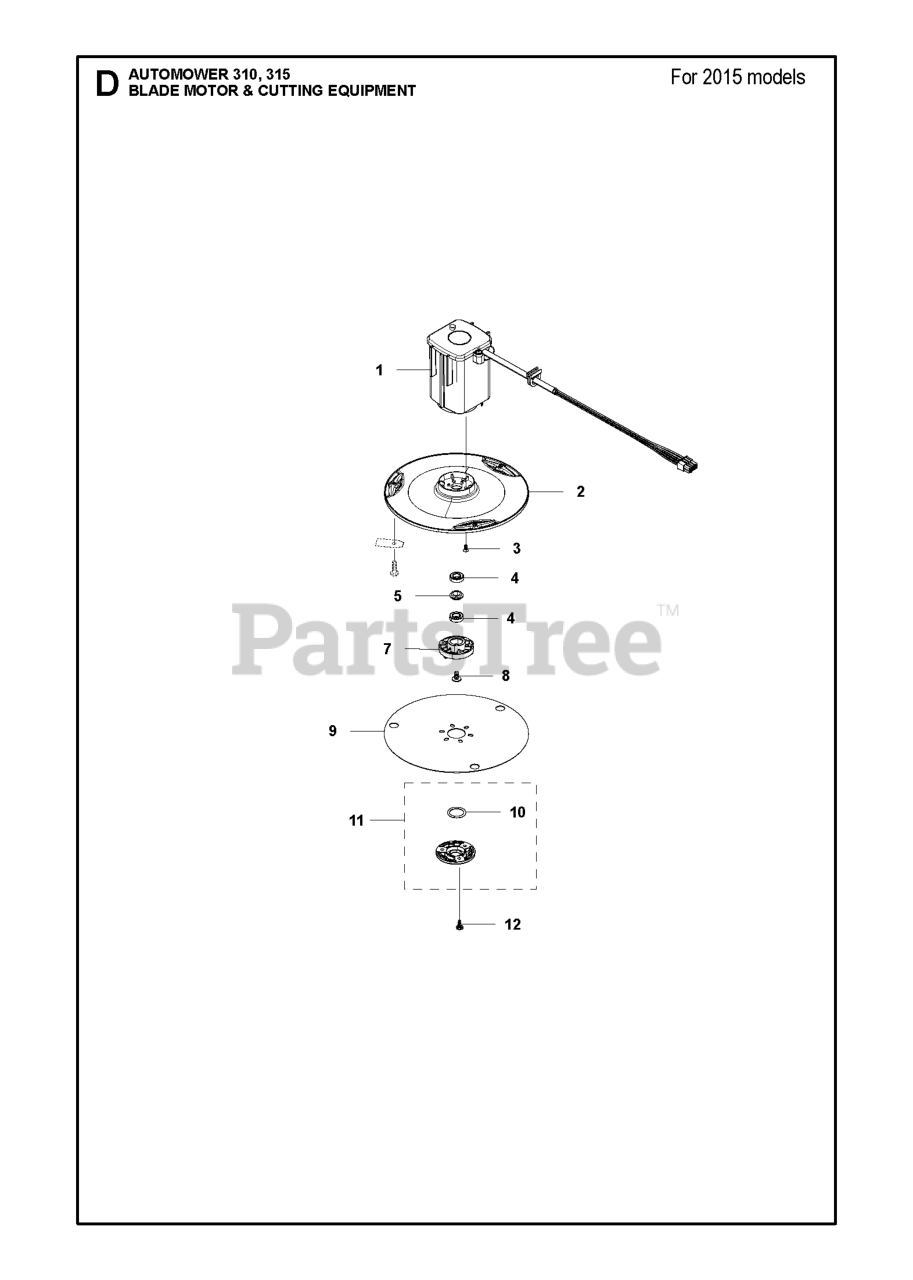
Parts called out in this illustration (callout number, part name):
1	MOTOR ASSY
2	CUTTING DISC CUTTING WIDTH 22
3	SCREW
4	BALL BEARING 2 RS,TIGHT CLEAR
4	BALL BEARING BALL BEARING 535
5	SLEEVE 10X5 MM
7	BEARING HOUSING SKID PLATE
9	SKID PLATE
10	O-RING 20X2,5 MM
11	COVER KIT BEARING
12	SCREW 14MM
